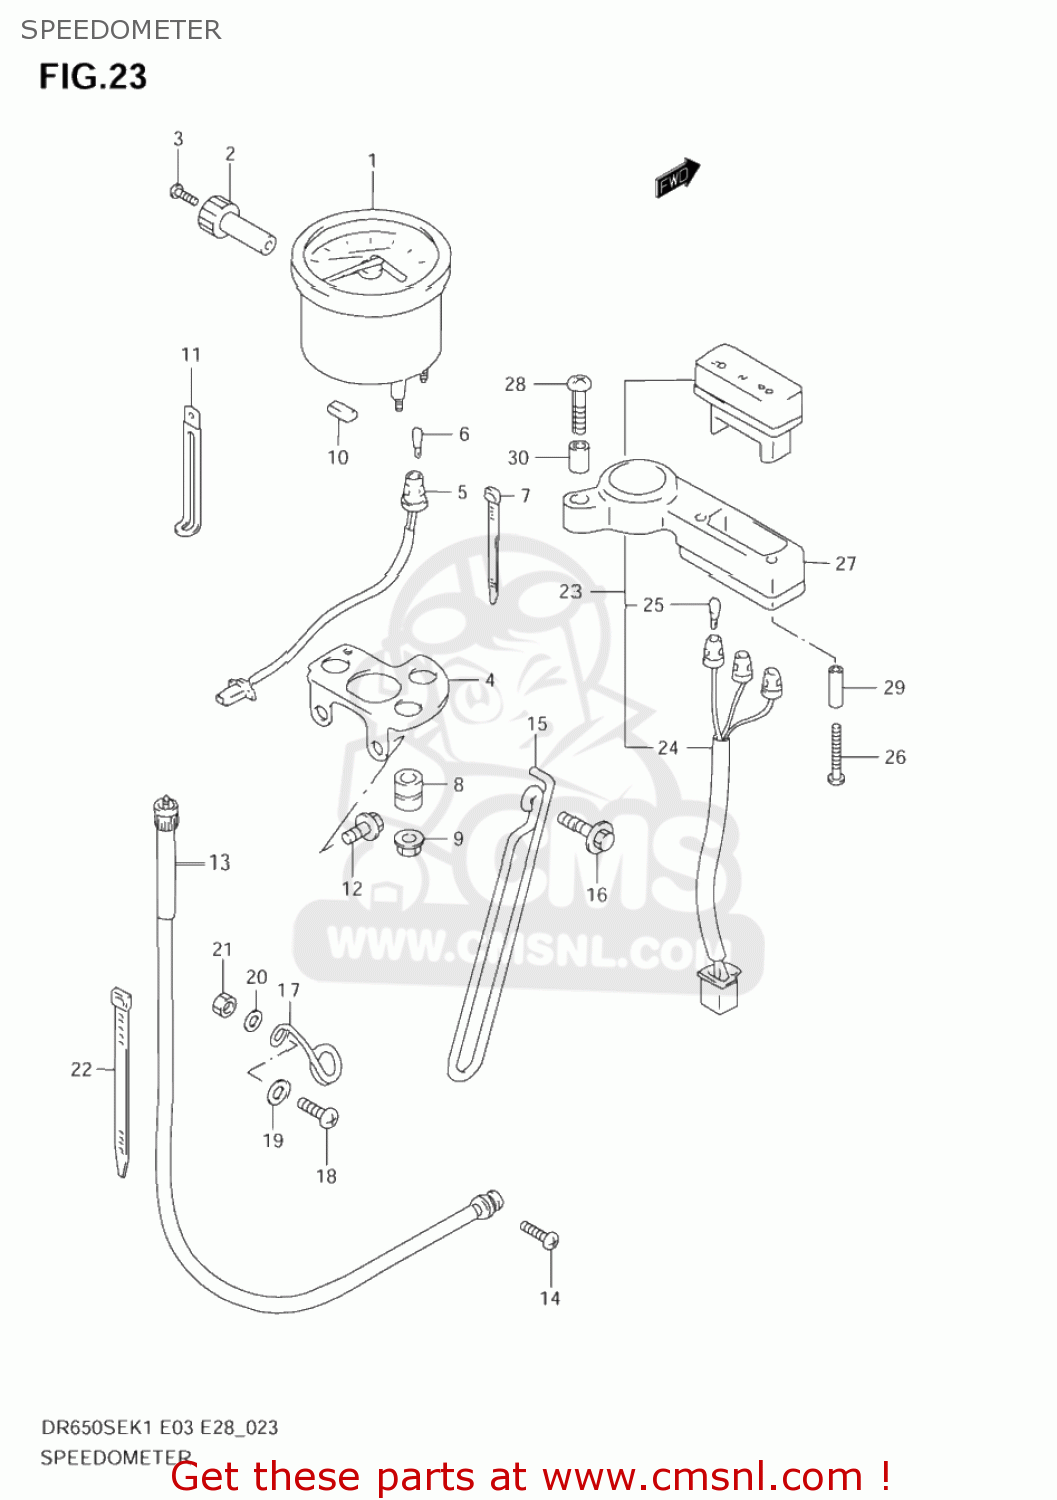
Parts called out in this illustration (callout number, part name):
1	SPEEDOMETER
2	KNOB,TRIP
3	SCREW,TRIP KNOB
4	BRACKET,METER
5	SOCKET
6	BULB(12V1.7W,T6.5)
7	CLAMP
8	CUSHION
9	NUT
10	CUSHION
11	CLAMP(L:97)
12	BOLT
13	CABLE ASSY,SPEEDOMETER
14	SCREW
15	GUIDE,METER CABLE NO.2
16	BOLT(6X20)
17	GUIDE,SPEEDOMETER CABLE
18	SCREW
19	WASHER(6.5X18X1.6)
20	WASHER
21	NUT 6MM
22	CLAMP(L:125)
23	BOX ASSY,PILOT LAMP
24	SOCKET & CORD
25	BULB(13.5V,2W,A7427)
26	SCREW
27	HOLDER,PILOT BOX
28	SCREW(6X25)
29	SPACER(4.5X6.5X25)
30	SPACER(6.1X8X15.5)
